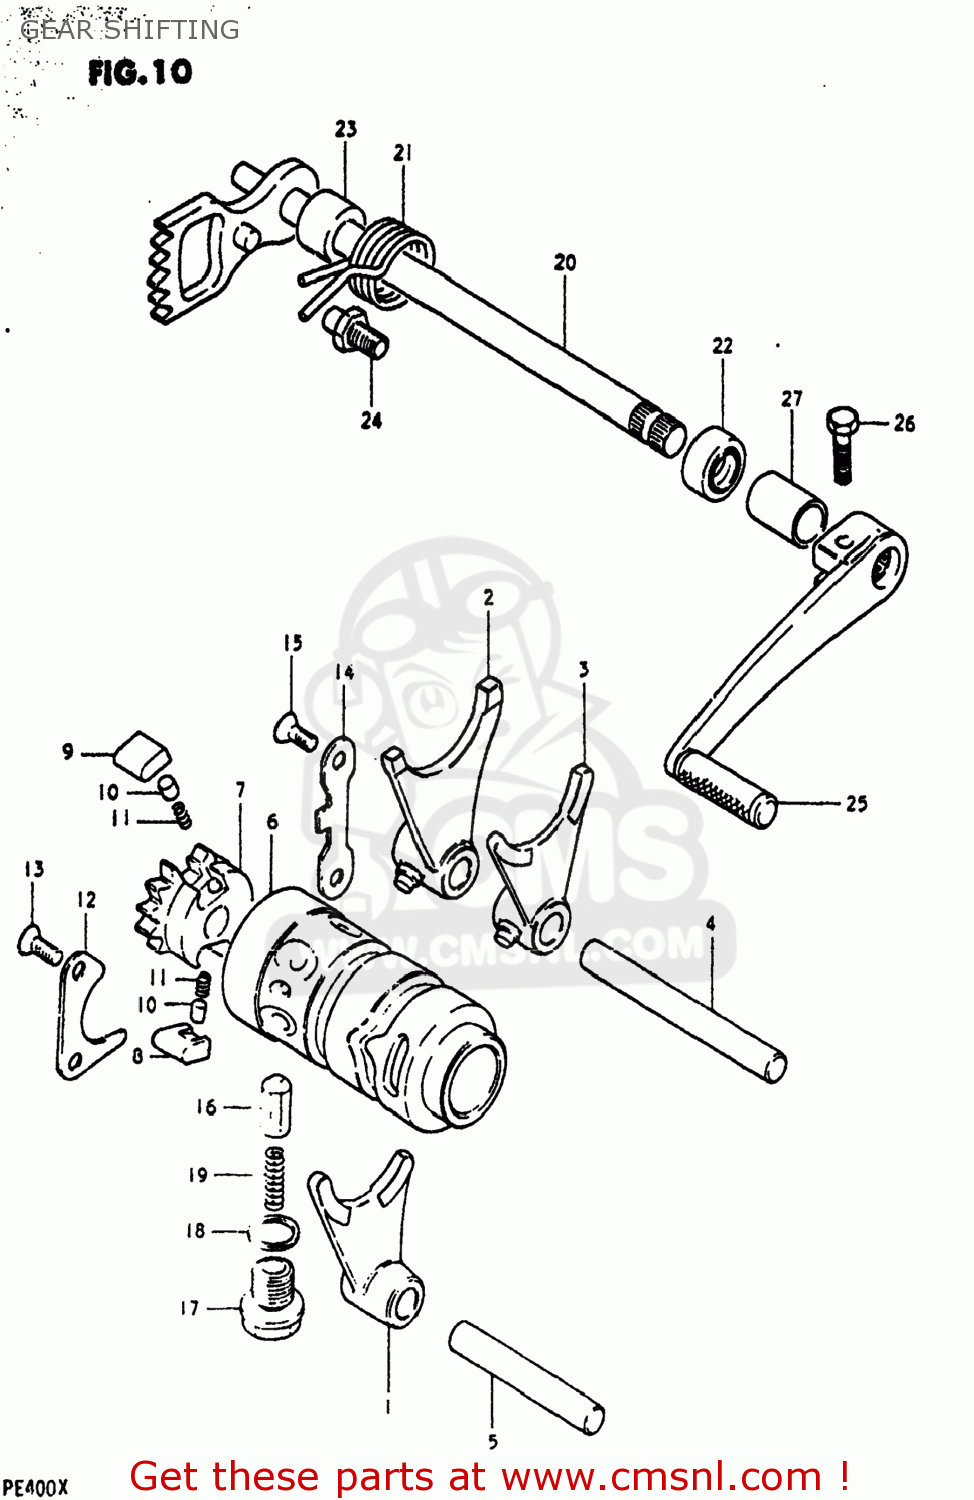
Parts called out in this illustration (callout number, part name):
1	FORK,GEAR SHIFT NO.1
2	FORK,GEAR SHIFT NO.2
3	FORK,GEAR SHIFT NO.3
4	SHAFT,GEAR SHIFT FORK
5	SHAFT,GEAR SHIFT FORK
6	CAM,GEAR SHIFT
7	RETAINER,GEAR SHIFT CAM
8	PAWL,GEAR SHIFT NO.1
9	PAWL,GEAR SHIFT NO.2
10	PIN(5X8)
11	SPRING
12	LIFTER,GEAR SHIFT PAWL
13	SCREW
14	GUIDE,GEAR SHIFT CAM
15	SCREW
16	STOPPER,GEAR SHIFTING
17	BOLT,GEAR SHAFT CAM STOPPER
18	GASKET(14X19.2X2) (NAS)
19	SPRING
20	SHAFT,GEAR SHIFT
21	SPRING
22	OIL SEAL
23	SPACER(12X20X15.3)
24	STOPPER,GEAR SHIFT CAM
25	LEVER ASSEMBLY,GEAR SHIFTING
26	BOLT
27	CUSHION
